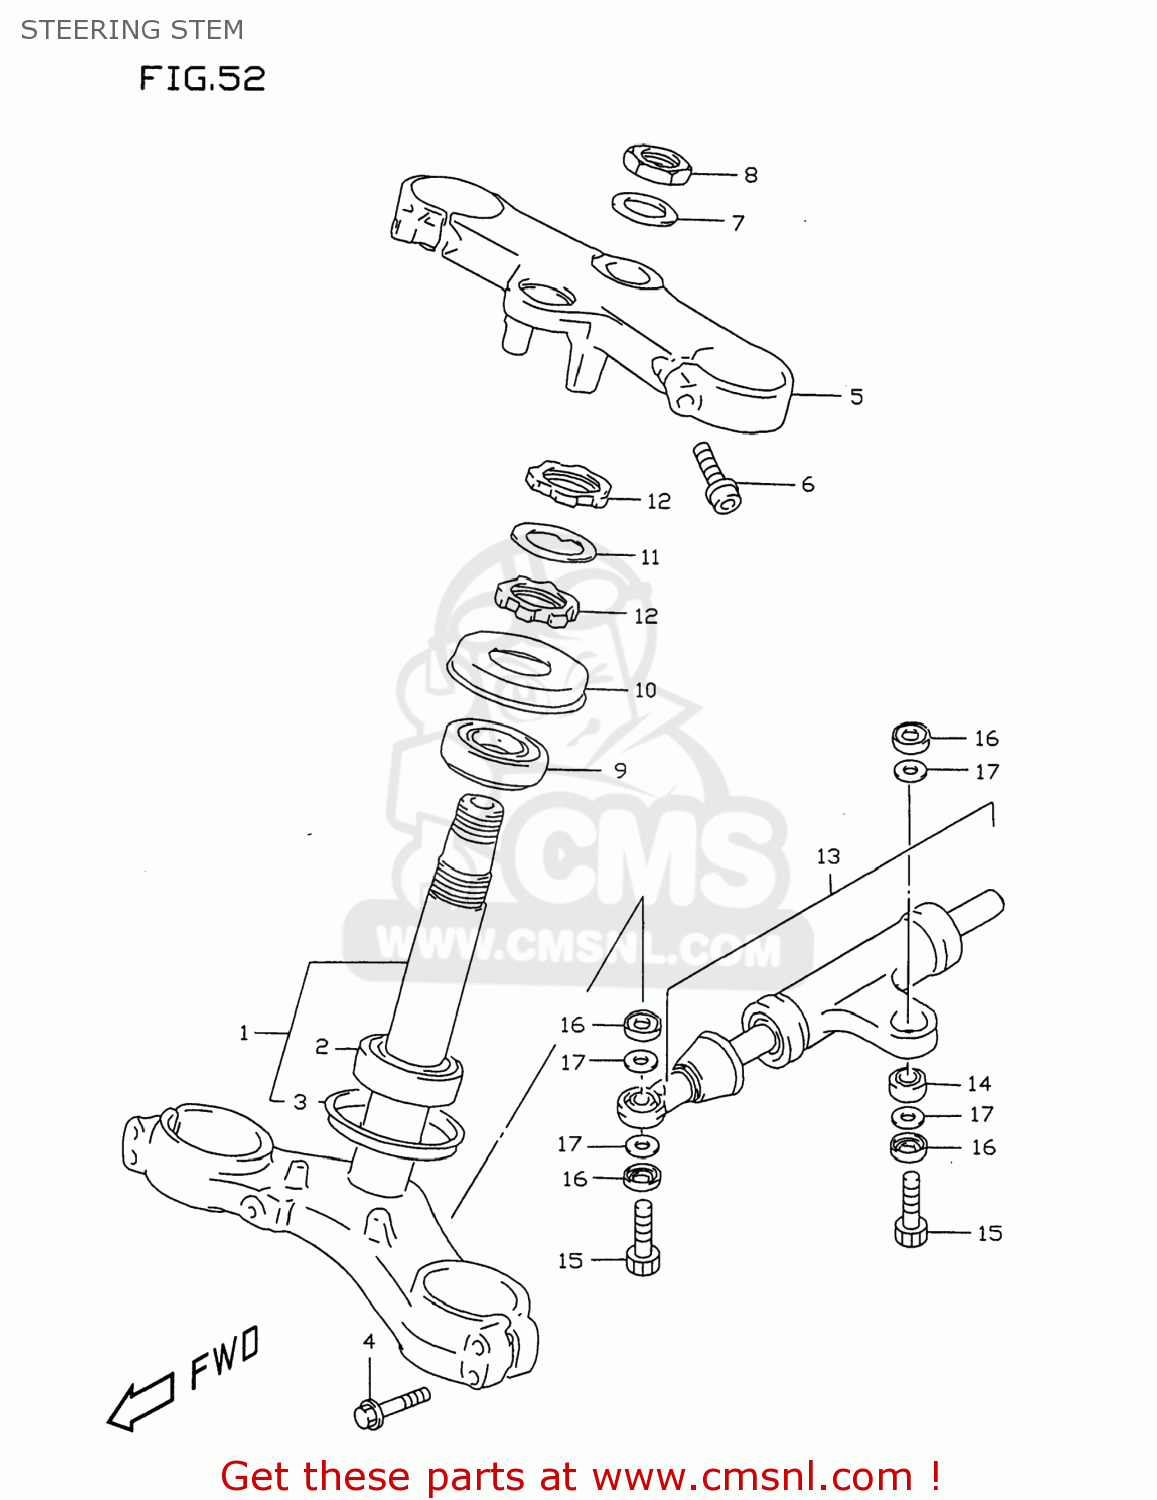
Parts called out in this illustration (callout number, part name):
1	STEM,STEERING
2	BEARING(30X55X17)
3	SEAL,STEERING LWR
4	BOLT
5	HEAD,STEERING STEM
6	BOLT
7	WASHER
8	NUT,STEM HEAD
9	BEARING(30X55X17)
10	SEAL,STEERING UPR DUST
11	WASHER,STEERING STEM
12	NUT,STEERING STEM
13	DAMPER ASSY,STEERING
14	BEARING(8X17.5X11)
15	BOLT
16	17
17	SHIM(8X12X0.8)
